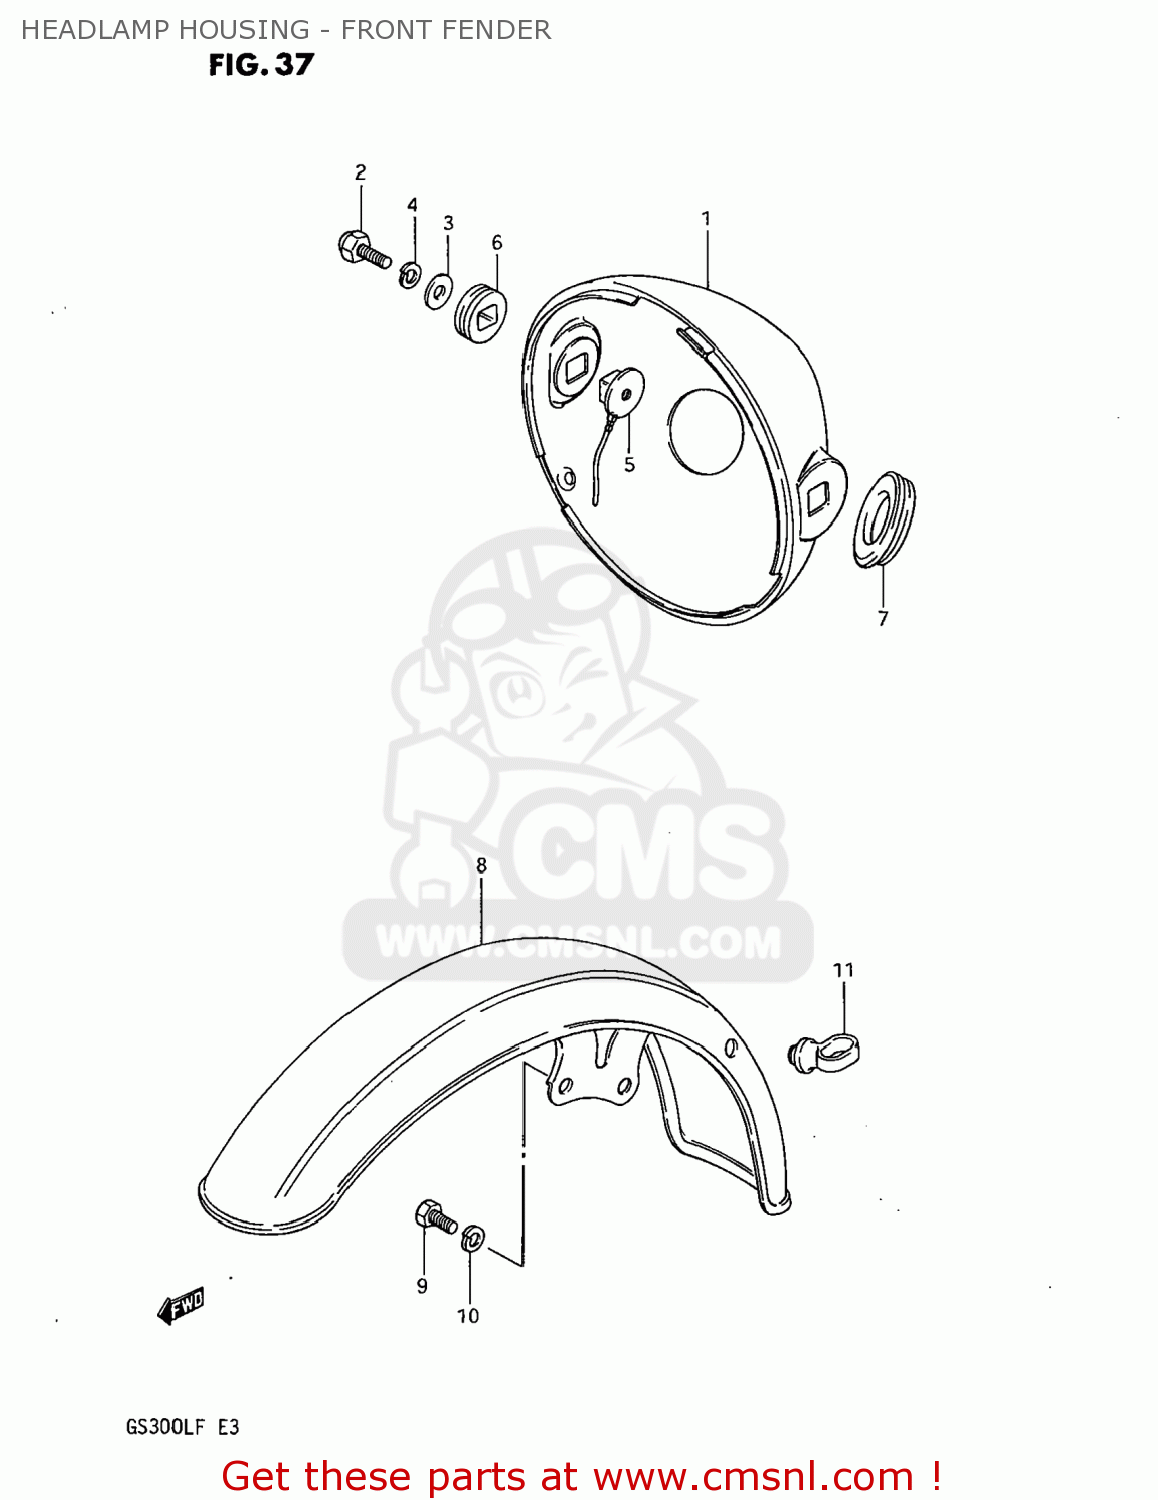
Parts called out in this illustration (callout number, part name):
1	HOUSING,HEADLAMP
2	BOLT
3	WASHER
4	LOCK WASHER
5	SPACER,HEADLAMP HOUSING
6	CUSHION,HEADLAMP HOUSING
7	GROMMET,HEADLAMP HOUSING
8	FENDER,FRONT
9	BOLT
10	LOCK WASHER
11	GUIDE,CABLE
